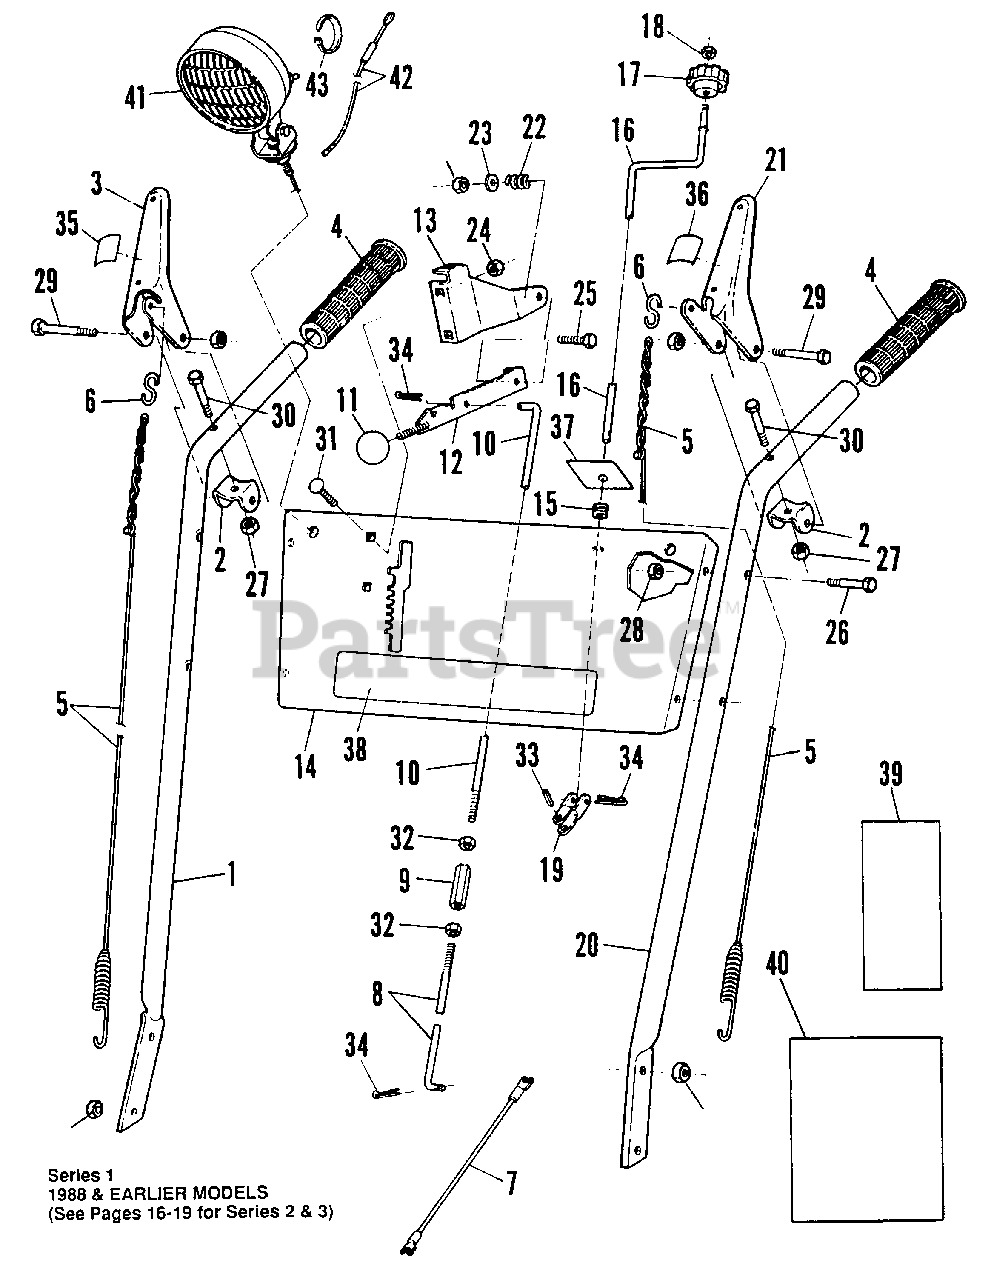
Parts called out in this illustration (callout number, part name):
1	BAR, Right Side Handle
2	BRACKET, Handle
3	HANDLE, Right Side
4	GRIP, Handle
5	CABLE, Clutch
6	"S"-HOOK
7	WIRE, Ground
8	ROD, Lower Shift
9	CONNECTOR
10	ROD, Upper Shift
11	KNOB, Shift Handle
12	HANDLE, Shift
13	BRACKET, Shift Lever
14	PANEL, Control
15	BUSHING
16	CRANK, Chute
17	KNOB, Chute Crank
18	NUT, 5/16-18 Hex Center Lock
19	CONNECTOR, Chute Crank
20	BAR, Left Side Handle
21	HANDLE, Left Side
22	SPRING, Shift Lever
23	WASHER, 5/16 Flat
24	NUT, 1/4-20 Hex Flange Lock
25	SCREW, 5/16-18 x 1-1/4" Hex Head Cap
26	SCREW, 5/16-24 x 1-1/2" Hex Head Cap
27	NUT, 1/4-28 Hex Top Lock
28	NUT, 5/16-24 Hex Center Lock
29	SCREW, 1/4-20 x 1/2" Hex Head Cap
30	SCREW, 1/4-28 x 1-3/8" Hex Head Cap
31	BOLT, 1/4-20 x 1/2" Carriage
32	NUT, 3/8-16 Hex
33	PIN, 1/8" x 1" Roll
34	PIN, 1/8 x 1" Cotter
35	DECAL, Blower Clutch
36	DECAL, Traction
37	DECAL, Chute Control
38	DECAL, SNAPPER
39	DECAL, Directional Control
40	DECAL, Instruction
41	ASSEMBLY, Light
42	HARNESS, Wire
43	TIE, Cable
